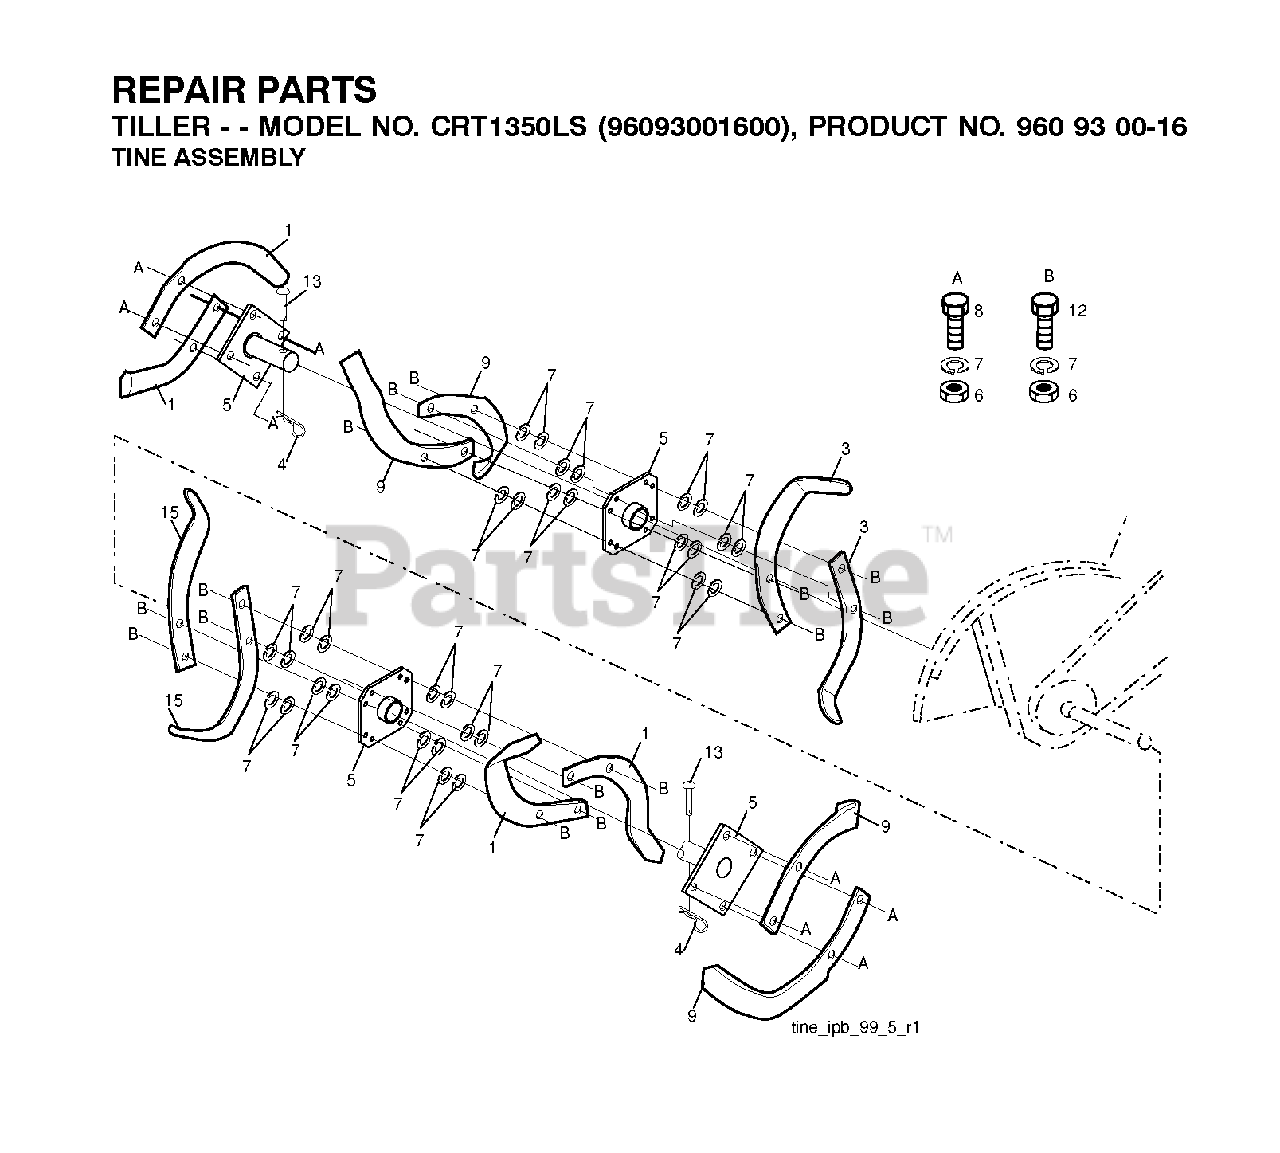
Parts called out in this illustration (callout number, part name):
1	TINE, LH 14"
3	TINE.LH.14".CRT
4	SPRING RETAINER
5	TINE.HUB.ASM.W/SHEILD
6	NUT
7	WASHER, LOCK 3/8
8	BOLT.HEX.001X20.37-24X1.ZINC
9	TINE, RH 14"
12	BOLT.3/8-24X1-1/2
15	TINE.RH.14".CRT
